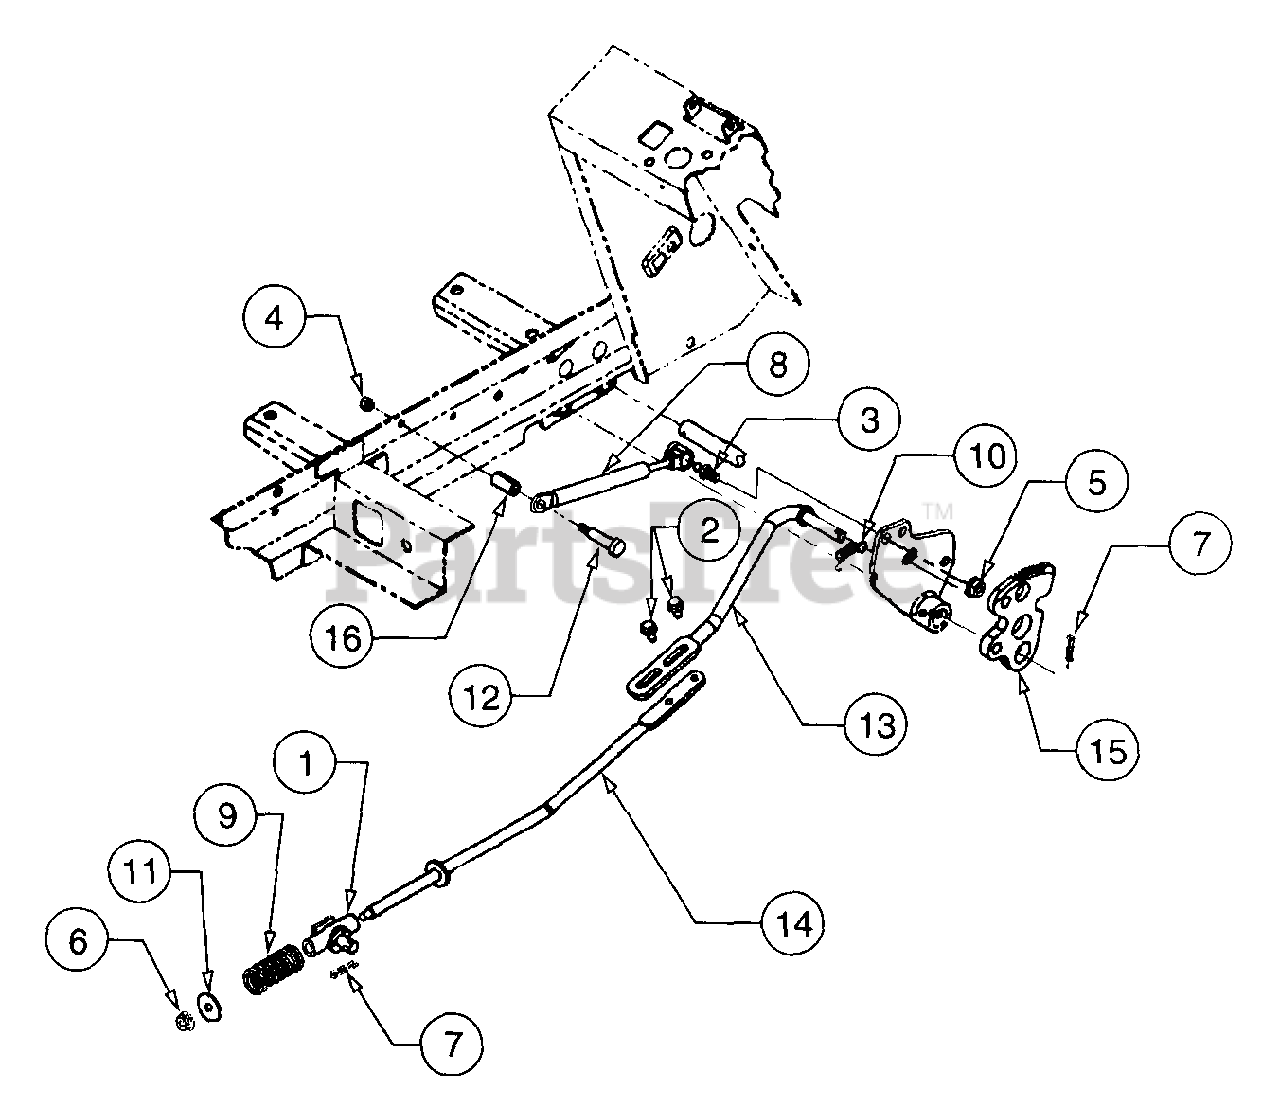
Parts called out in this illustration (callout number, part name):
1	Pivot Assembly
2	Screw, Hex Wash Hd Tapp 1/4-20 x .5
3	Screw, Ball, 5/16-18 x .56
4	Nut, Hex Sems, 1/4-20
5	Nut, Hex Flange Lock, 5/16-18 GR5
6	Nut, Hex Flange Lock, 1/4-20
7	Pin, Internal Cotter
8	Cylinder, Damper
9	Spring, Compression, .63 ID x 2.0 Lg
10	Spring, Extension, 3/8 OD x 1.44
11	Washer, Flat, .265 x 1.0 x .030
12	Bolt, Shoulder, .374 Dia x 1.375
13	Rod, Front Control
14	Rod, Rear Hydro Control
15	Plate, Cruise
16	Spacer, Split Tubing, .375 ID x 1.04
